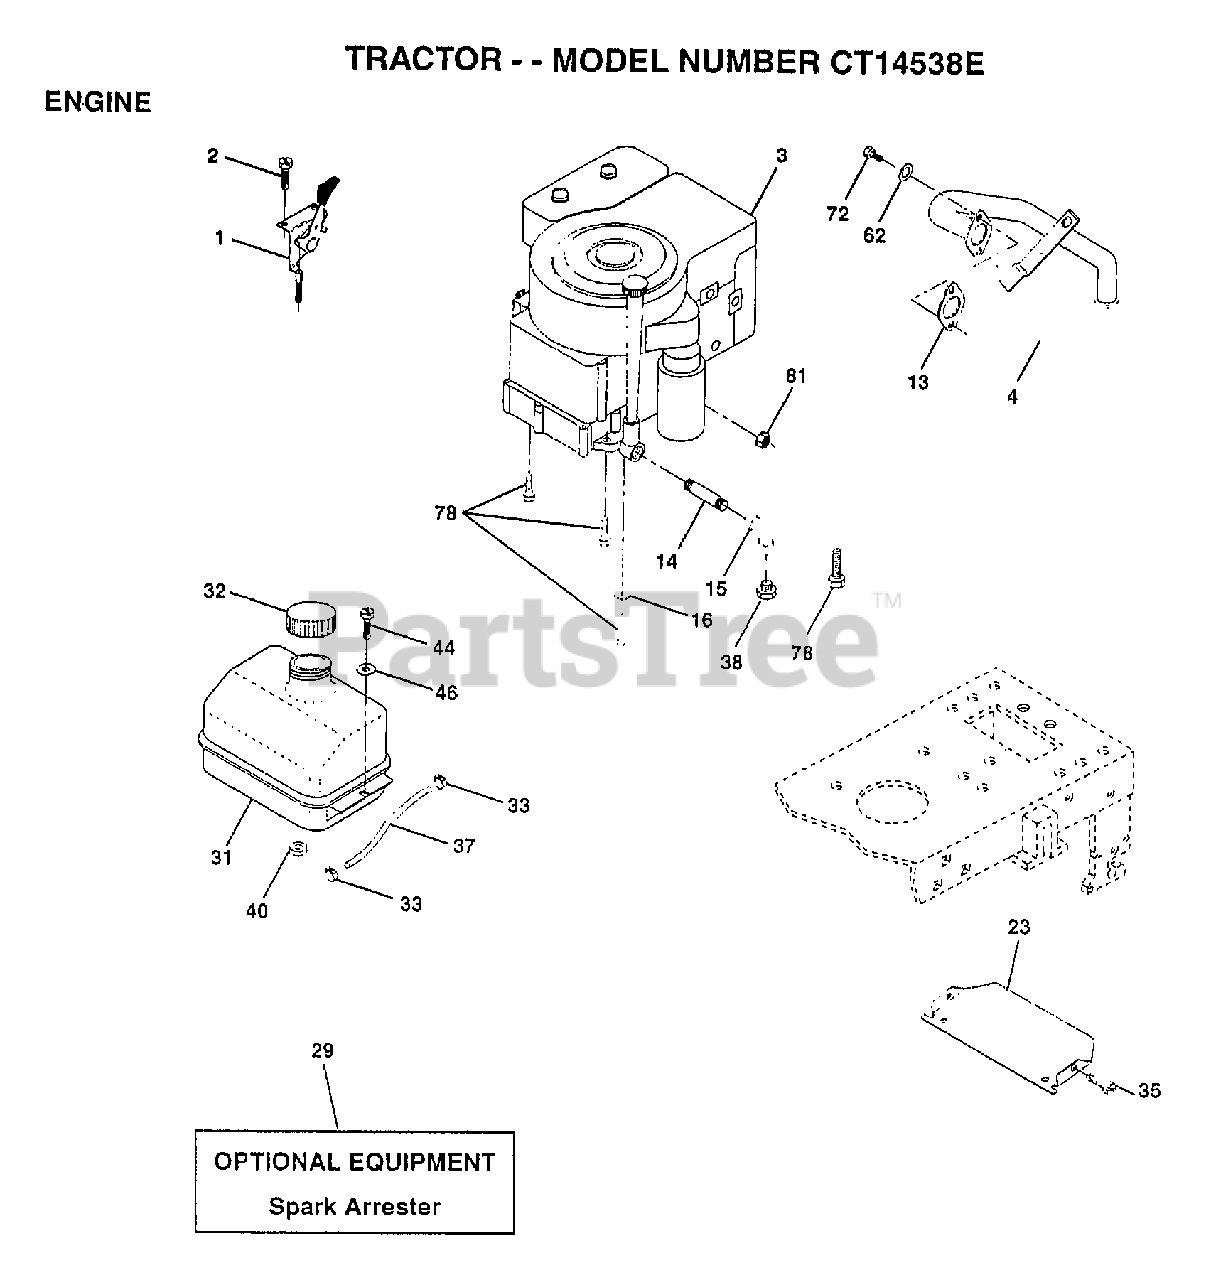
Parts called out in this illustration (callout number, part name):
1	THROTTLE CONTROL
2	SCREW LT
4	MUFFLER
13	GASKET ENG 1 313 LD TIN PLATED
14	PIPE NIPPLE
15	ELBOW
16	LOCKWASHER
23	SHIELD-HEAT
31	TANK.FUEL.LT.
32	CAP ASM FUEL
33	HOSE CLAMP
35	SCREW
37	LINE FUEL
44	SCREW HEX CRT
46	WASHER
62	LOCKWASHER
72	SCREW
78	SCREW
81	NUT
